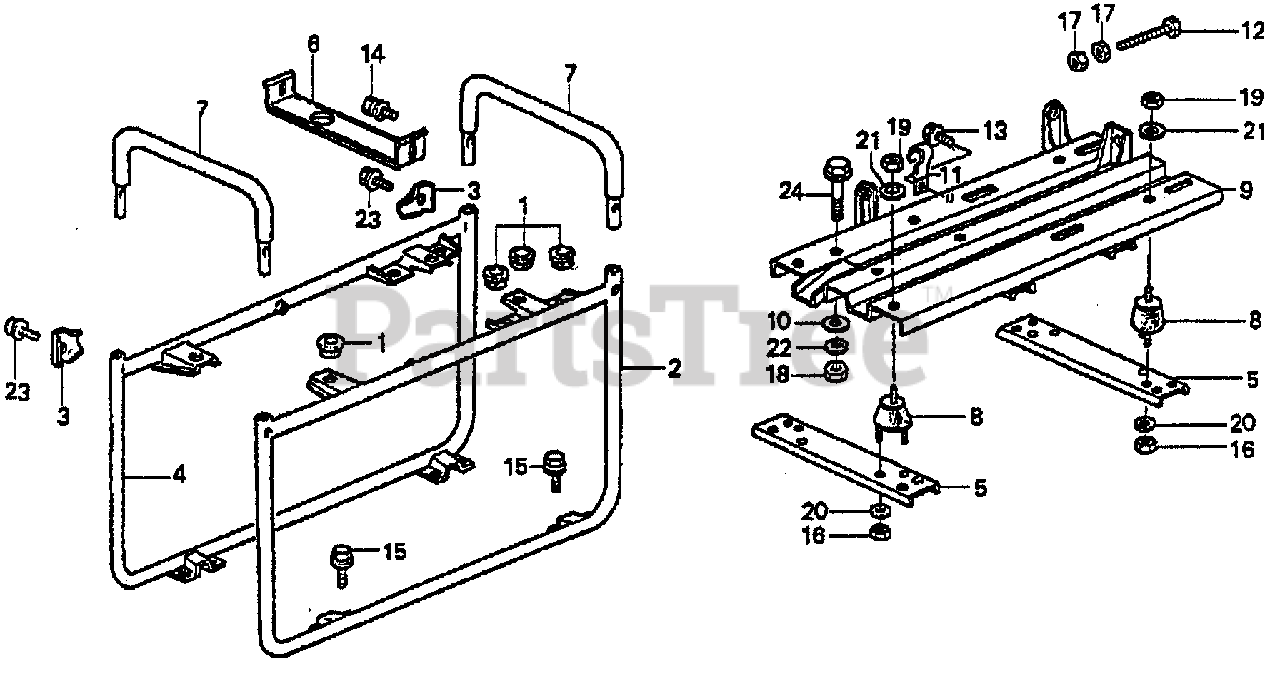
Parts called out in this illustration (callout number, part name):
1	RUBBER, TANK CUSHION
2	FRAME, FR. PIPE (NOT AVAILABLE)
3	PLATE, JOINT
4	PIPE FRAME, RR.
5	PLATE (LOWER)
6	STOPPER, ENGINE (NOT AVAILABLE)
7	HANDLEBAR (NOT AVAILABLE)
8	RUBBER, ENGINE SETTING
9	BED, ENGINE (NOT AVAILABLE)
10	WASHER, EX. MANIFOLD
11	CLIP, CORD
12	BOLT, HEX. (8X80)
13	BOLT-WASHER (6X12)
13	BOLT, FLANGE (6X12)
14	BOLT-WASHER (6X12)
15	BOLT-WASHER (8X16)
16	NUT, HEX. (6MM)
17	NUT, HEX. (8MM)
18	NUT, HEX. (10MM)
19	NUT, HEX. (8MM)
20	WASHER, PLAIN (6MM)
21	WASHER, PLAIN (8MM)
22	WASHER, SPRING (10MM)
23	BOLT, FLANGE (8X16)
24	BOLT, FLANGE (10X40)
